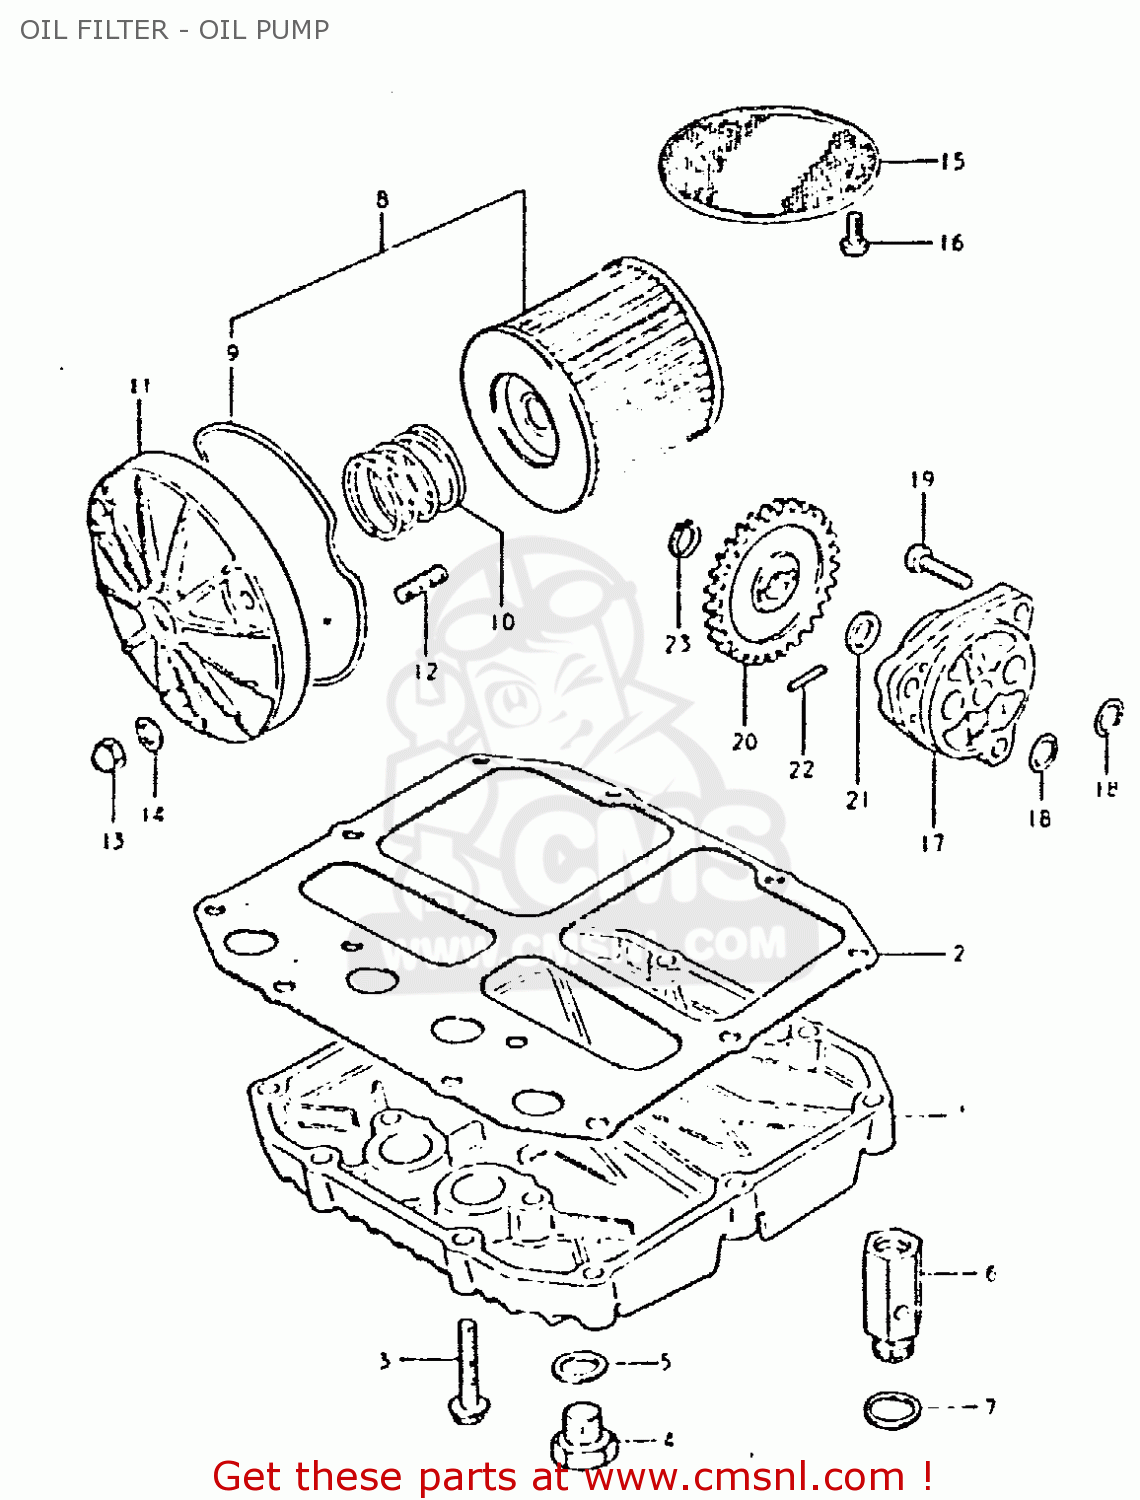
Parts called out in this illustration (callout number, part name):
1	PAN,OIL
2	GASKET,OIL PAN (MCA)
3	BOLT
4	PLUG
5	GASKET(14X19.2X2) (NAS)
6	REGULATOR ASSEMBLY,ENGINE
7	WASHER
8	ENGINE OIL FILTER SET
9	O RING,OIL FILTER CHAMBER CAP
10	SPRING
11	CAP,ENGINE OIL FILTER
12	STUD 6X20
13	NUT
14	WASHER
15	STRAINER,ENGINE OIL
16	SCREW 6X12
17	PUMP ASSY,ENGINE OIL
18	O RING(D:1.9,ID:13)
19	SCREW
20	GEAR,OIL PUMP DRIVEN
21	SHIM
22	PIN(4X15.8)
23	CIRCLIP
